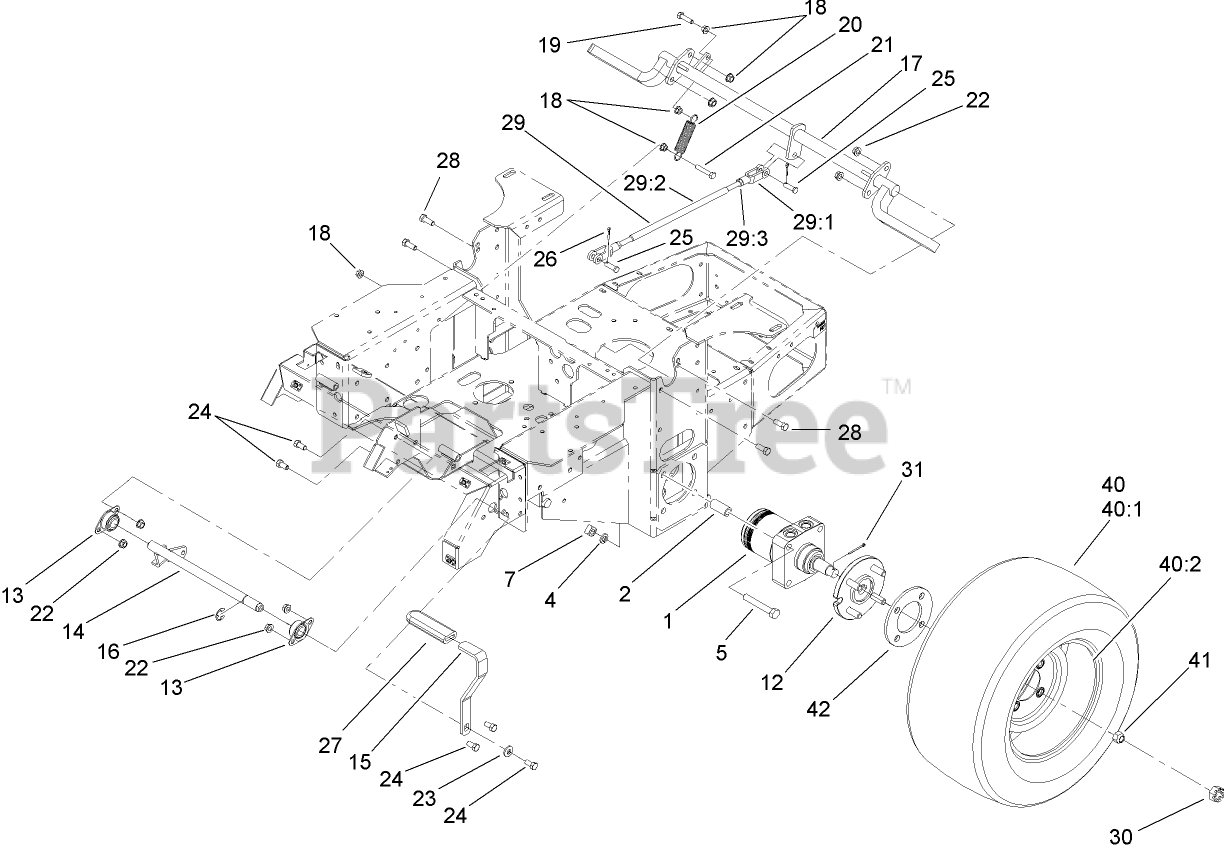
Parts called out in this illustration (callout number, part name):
1	MOTOR-WHEEL
2	SPACER-MOTOR, WHEEL
4	WASHER-LOCK
5	SCREW-HH
7	NUT-SQUARE
12	HUB ASM W/STUDS
13	BEARING-FLANGE, SIDE
14	Shaft-Brake, Parking
15	HANDLE-BRAKE, PARK
16	E-RING
18	NUT-HF
19	SCREW-HH
20	SPRING-IDLER
21	SCREW-HH
22	NUT-HHF, WHIZ
23	WASHER-BELLEVILLE
24	SCREW-HH
25	PIN-CLEVIS
26	PIN-COTTER
27	GRIP-LEVER
28	SCREW-HH
29	BRAKE ROD ASM
29:1	YOKE-LINKAGE, BRAKE
29:2	LINKAGE-HANDLE, BRAKE
29:3	NUT-HEX
30	NUT-HEX, SLOTTED
31	PIN-COTTER
40	WHEEL AND TIRE ASM
40:1	TIRE
41	NUT-LUG
42	SPACER-WHEEL
